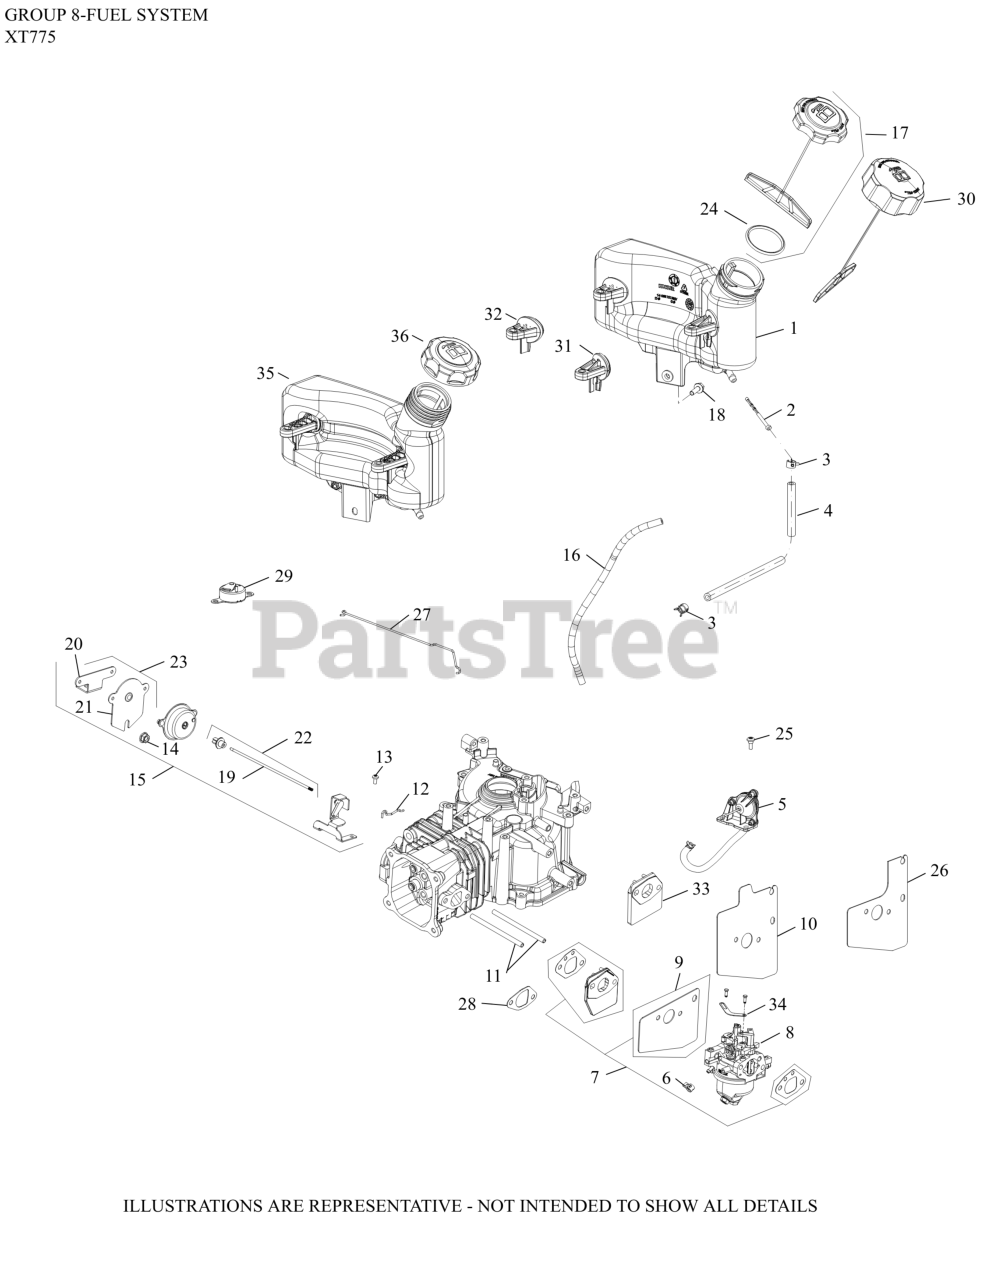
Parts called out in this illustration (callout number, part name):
1	TANK, FUEL 1.4L FOR EUROPE ONLY
2	FILTER, FUEL IN-NIPPLE
3	CLAMP, HOSE (NON-CALIF)(#1423710S)
4	HOSE, FUEL LOW-PERMEATION
7	KIT, SPACER
8	KIT, CARBURETOR 13 MM STD CHOKE
9	KIT, CARBURETOR HEAT SHIELD GASKET
11	STUD,M6X1.0X100.2MM
16	HOSE, EVAPORATIVE
17	CAP ASSEMBLY, FUEL
18	SCREW, HEX FLANGE (M6)
24	SEAL, FUEL CAP
28	KIT, INTAKE GASKET
NI	TOOL, SPARK PLUG WRENCH ASSY
NI	KIT, HIGH ALTITUDE - USE 14 755 04-S
NI	KIT, CARBURETOR REPAIR (RUIXING)
